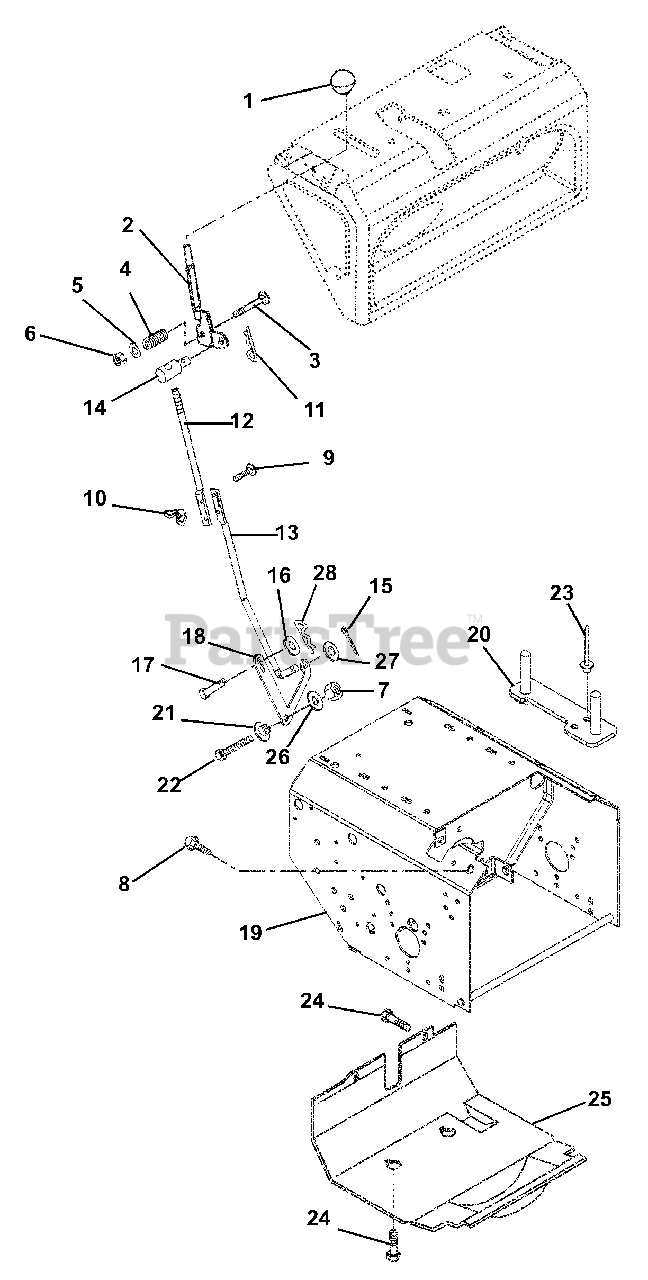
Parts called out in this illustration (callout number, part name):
1	Knob, Ball Black 1-.41, .38-16
2	Lever, Shift Weldment
3	Bolt, Round Head Square Neck .38-16 x 2.50 Grade 5
4	Spring, Compression .13 x .78 x 1.25
5	Washer, Flat Steel .44 x 1.00 x .083
6	Nut, Locking Center .38-16
7	Nut, Locking Center .31-18
8	Bolt, Hex Flanged Whiz Lock Head .38-16 x .75
9	Bolt, Round Head Square Neck .25-20 x 1.00 Grade 5
10	Nut, Locking Wing .25-20
11	Pin, Hair Internal .08 x .18 x 1.18
12	Rod, Shift-Upper
13	Rod, Shift-Lower
14	Pivot, Rod
15	Pin, Cotter .12 x .75
16	Washer, Flat Steel .38 x .81 x .023
17	Clevis Pin .37/.38 x .69
18	Arm, Shift
19	Main Frame
20	Bolt Strap
21	Bushing, Flange .325 x .500 x .327 x .875
22	Bolt, Hex .31-18 x 1.00 Grade 5
23	Rivet, Pop
24	Screw, Tapping .312-12 x .375 Hex Washer
25	Cover, Bottom
26	Washer, Flat Steel .328 x .875 x .062
27	Washer, Flat-Steel .53 x 1.06 x .095
28	Pin, Hair
